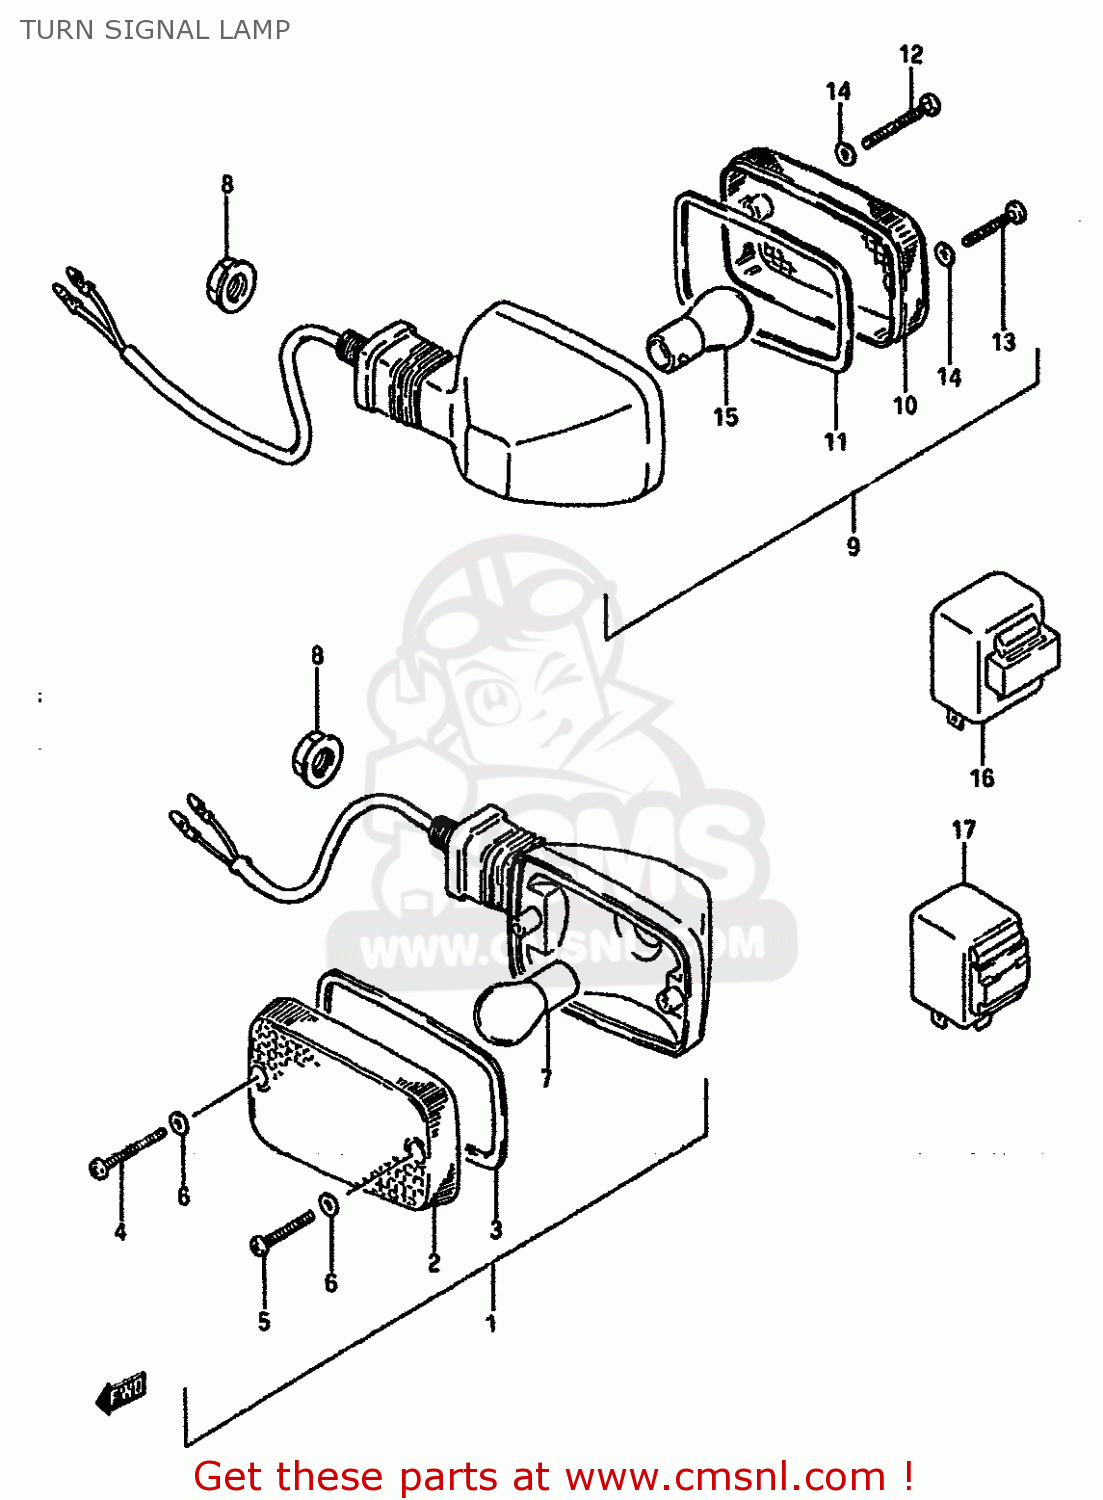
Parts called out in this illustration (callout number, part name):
1	LAMP ASSY,FR
2	LENS,FR
3	GASKET (NAS)
4	SCREW,TURN SIG LENS FITTING
5	SCREW
6	GASKET (NAS)
7	BULB(12V21W)
8	NUT
9	LAMP,RR TURNSI
10	LENS,RR
11	GASKET (NAS)
12	SCREW,TURN SIG LENS FITTING
13	SCREW
14	GASKET (NAS)
15	BULB(12V21W)
16	RELAY ASSEMBLY,TURN SIGNAL
17	RELAY ASSY,TUR
